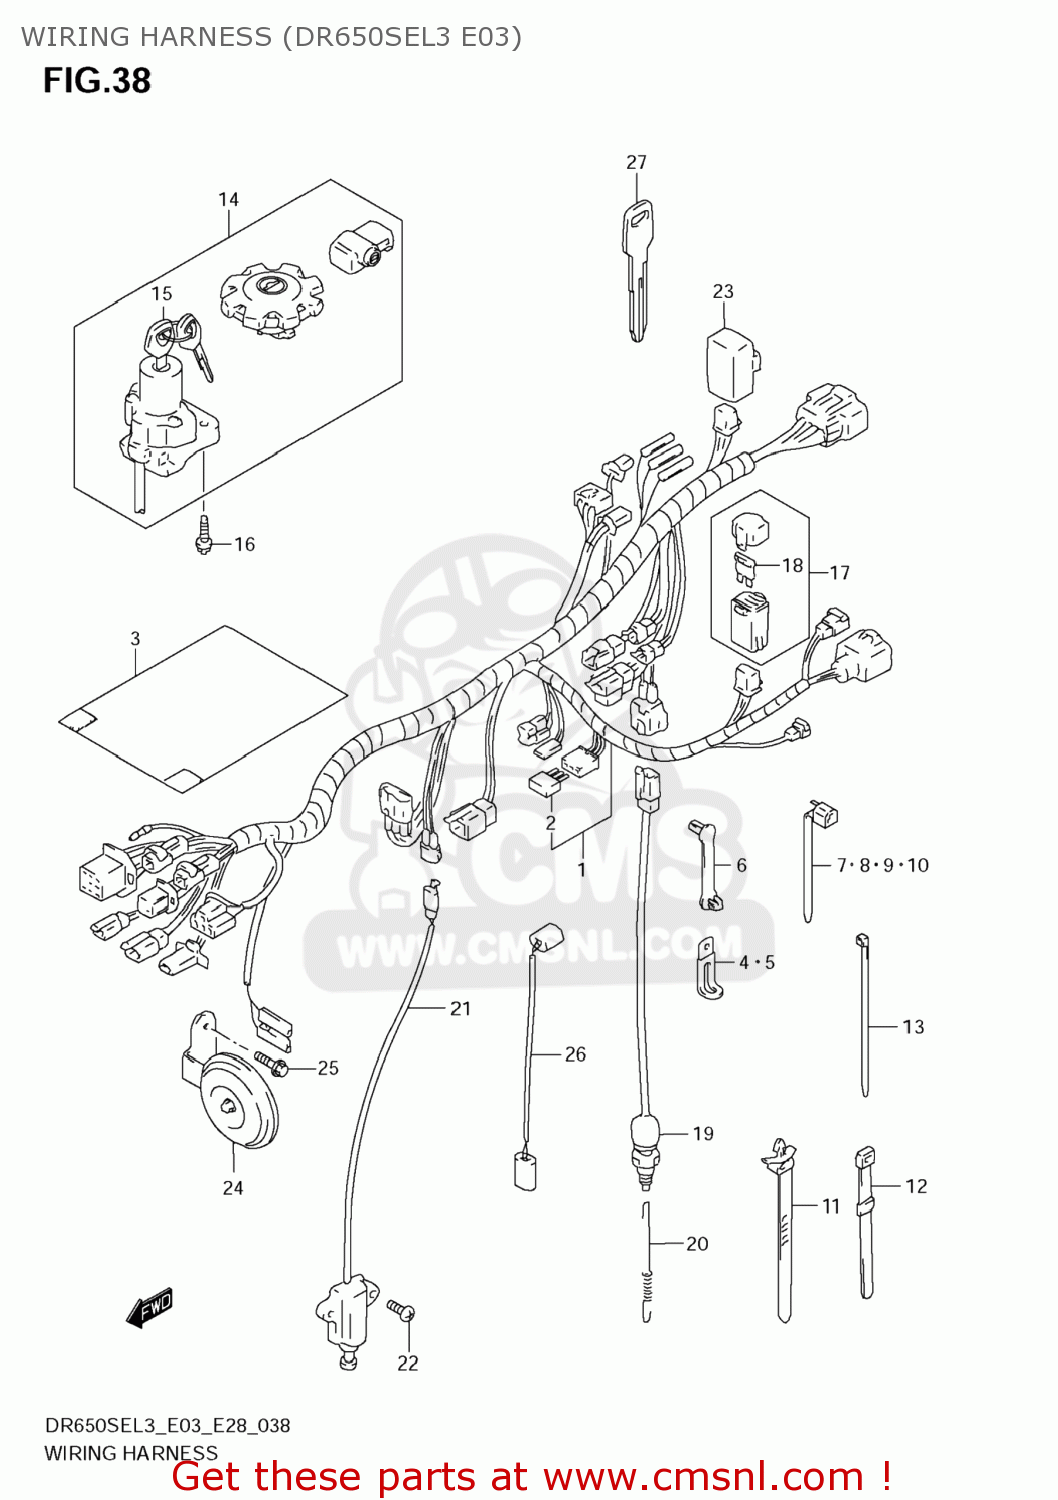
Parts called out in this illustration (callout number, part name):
1	HARNESS,WIRING
2	DIODE(STANLEY DE8804)
3	COVER,WIRING HARNESS
4	CLAMP(L:45)
5	CLAMP(L:80)
6	CLAMP(L:33)
7	CLAMP(L:95)
8	CLAMP(L:125)
9	CLAMP(L:165)
10	CLAMP(L:235)
11	CLAMP(L:90)
12	CLAMP(L:120)
13	CLAMP(L:100)
14	LOCK SET
15	LOCK ASSY,STEERING
16	BOLT(8X20)
17	BOX ASSY,FUSE
18	FUSE(10A)
19	SWITCH ASSY,STOP LAMP
20	SPRING
21	SWITCH ASSY,SIDE STAND
22	SCREW
23	RELAY ASSY
24	HORN ASSY
25	BOLT
26	WIRE,THROTTLE SENSOR
27	KEY,BLANK
